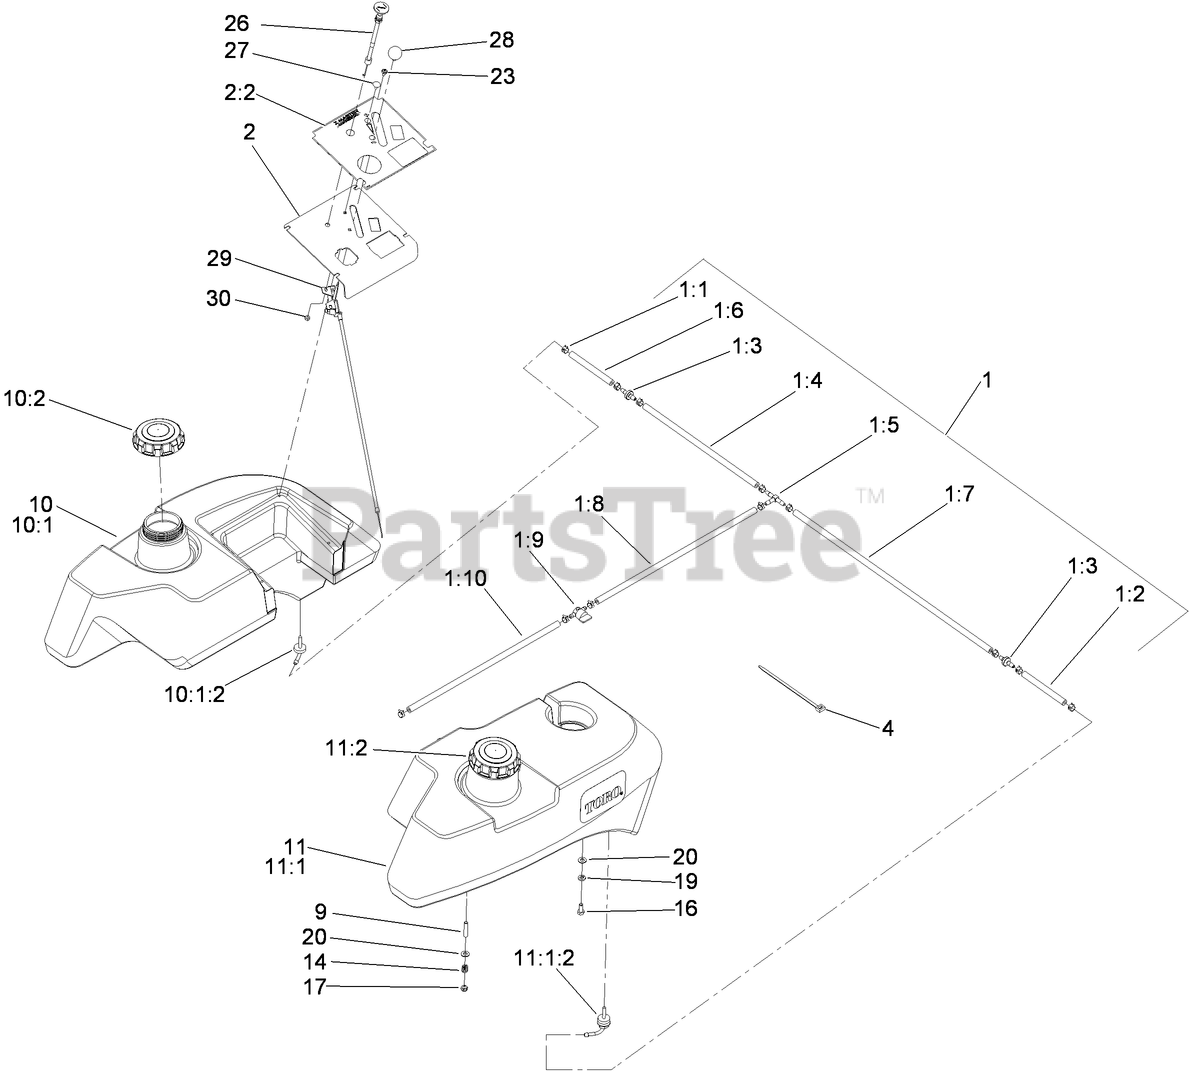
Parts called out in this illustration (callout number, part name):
1	FUEL LINE ASM
1:1	CLAMP-HOSE
1:2	HOSE-FUEL
1:3	VALVE-CHECK, FUEL
1:4	HOSE-FUEL
1:5	FITTING-TEE, BARBED
1:6	HOSE-FUEL
1:7	HOSE-FUEL
1:8	HOSE-FUEL
1:9	VALVE-FUEL
1:10	HOSE-FUEL
2	CONTROL PANEL ASM
2:2	DECAL-PANEL, CONTROL
4	TIE-PLASTIC
10	LH FUEL TANK KIT
10:1	LH FUEL TANK ASM
10:1:2	FITTING-FUEL, BULKHEAD
10:2	CAP-FUEL, GAS
11	RH FUEL TANK KIT
11:1	RH FUEL TANK ASM
11:1:2	FITTING-FUEL, BULKHEAD
11:2	CAP-FUEL, GAS
14	SPRING-TANK, FUEL
16	SCREW-HH
17	NUT-LOCK, NI
19	WASHER-LOCK
20	WASHER-PLAIN
23	SCREW-PPH
26	Control-Choke, Push / Pull
27	BOLT-CARR
28	KNOB-BALL
29	CABLE-THROTTLE
30	NUT-LOCK, NI
